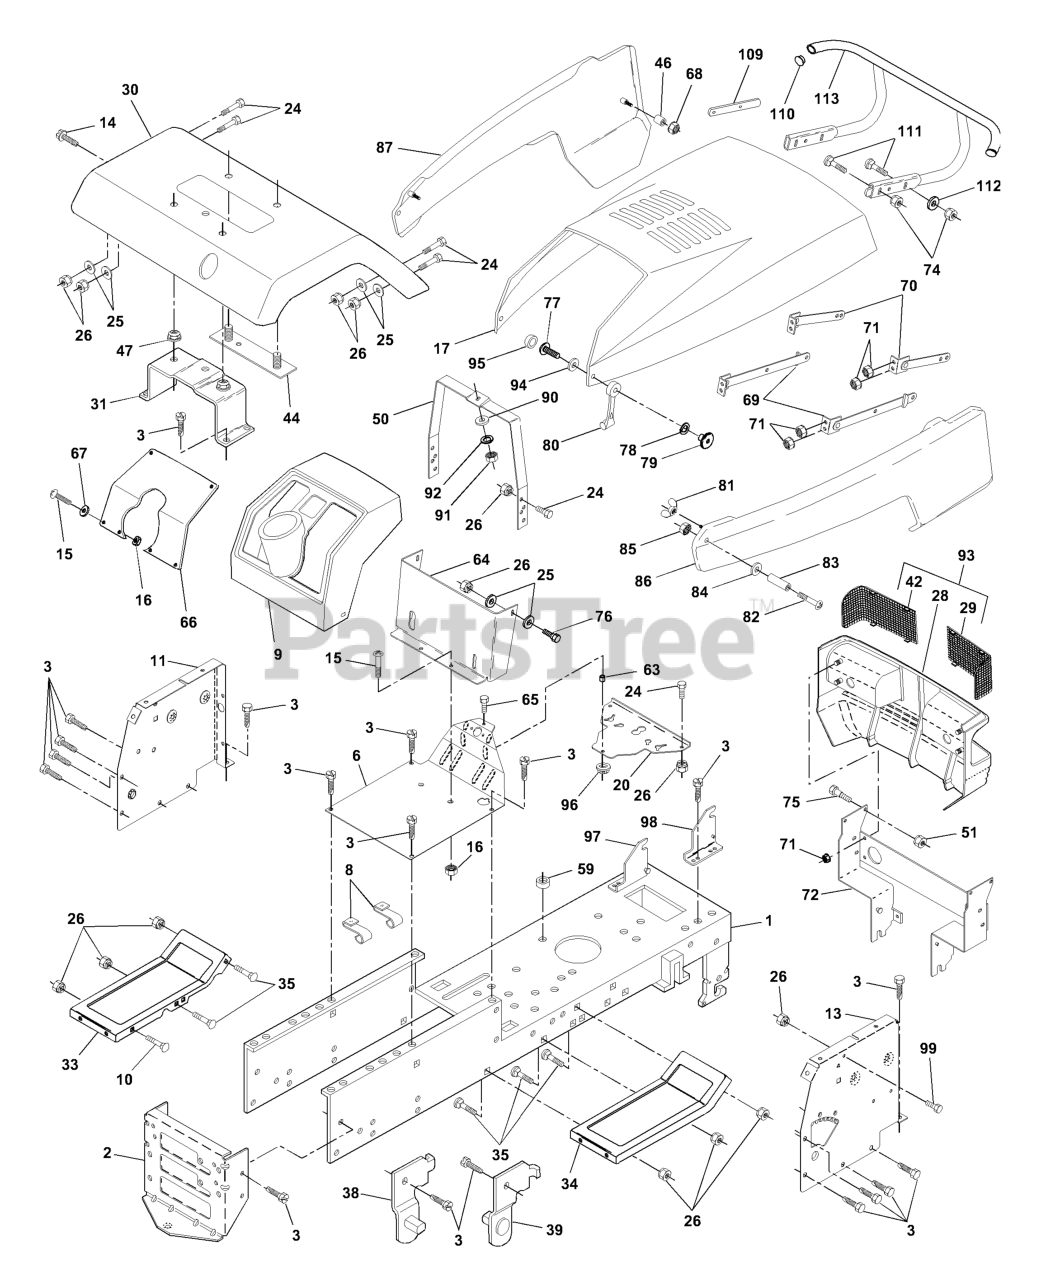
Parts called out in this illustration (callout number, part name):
1	CHASSIS
2	STRETCH DRAWBAR
3	SCREW
8	CLIP,INSULATOR
10	BOLT D
11	PANEL DASH LH
13	PANEL DASH RH
14	SCREW LT
15	Screw, Machine 5/16-18 UNC x 3/4
16	NUT
17	HOOD.HUSQVARNA.ORANGE
20	PLATE, BATTERY
24	BOLT
25	WASHER
26	NUT
28	GRILL
29	LENS RH
30	FENDER
31	FENDER BRKT
33	ROLL PIN NLA
34	PAD,SPACER
35	BOLT
38	BRACKET LH PIVOT
39	BRACKET RH PIVOT
42	LENS LH
44	STRAP
47	NUT-PUSH YT
50	SUPPORT ASS'Y
51	LOCKNUT.NYLOC.1/4-20
59	SNAP BUSHING T
64	DASH LOWER YT NLA
65	Bolt, Hex, Fin. 5/16-18 UNC x 2
66	DASH PLATE
67	WASHER
68	NUT
69	STRAP ASSY LT
70	STRAP ASSY LT
71	Nut, Keps Blk Hex 1/4-20 UNC
72	SUPPORT ASS'Y
75	BOLT T
76	BOLT
77	SCREW
78	LOCKWASHER #10
79	WELDNUT
80	LATCH.HOOD.
81	WING NUT
82	RP SCREW
85	NUT **
86	SIDE PANEL ASSY RH
87	SIDE PANEL ASSY LH
90	WASHER PM
91	NUT
92	LOCKWASHER
93	GRILL COMPLETE
95	SNAP CAP LT
96	NUT.71038.31-18.HEX.NYLOCK
97	SUPPORT RH YTH
98	SUPPORT LH YTH
99	BOLT
109	BRACKET BUMPER
110	PLUG PLASTIC
111	BOLT.3/8-14X1.25
112	WASHER
113	BUMPER ASSY
